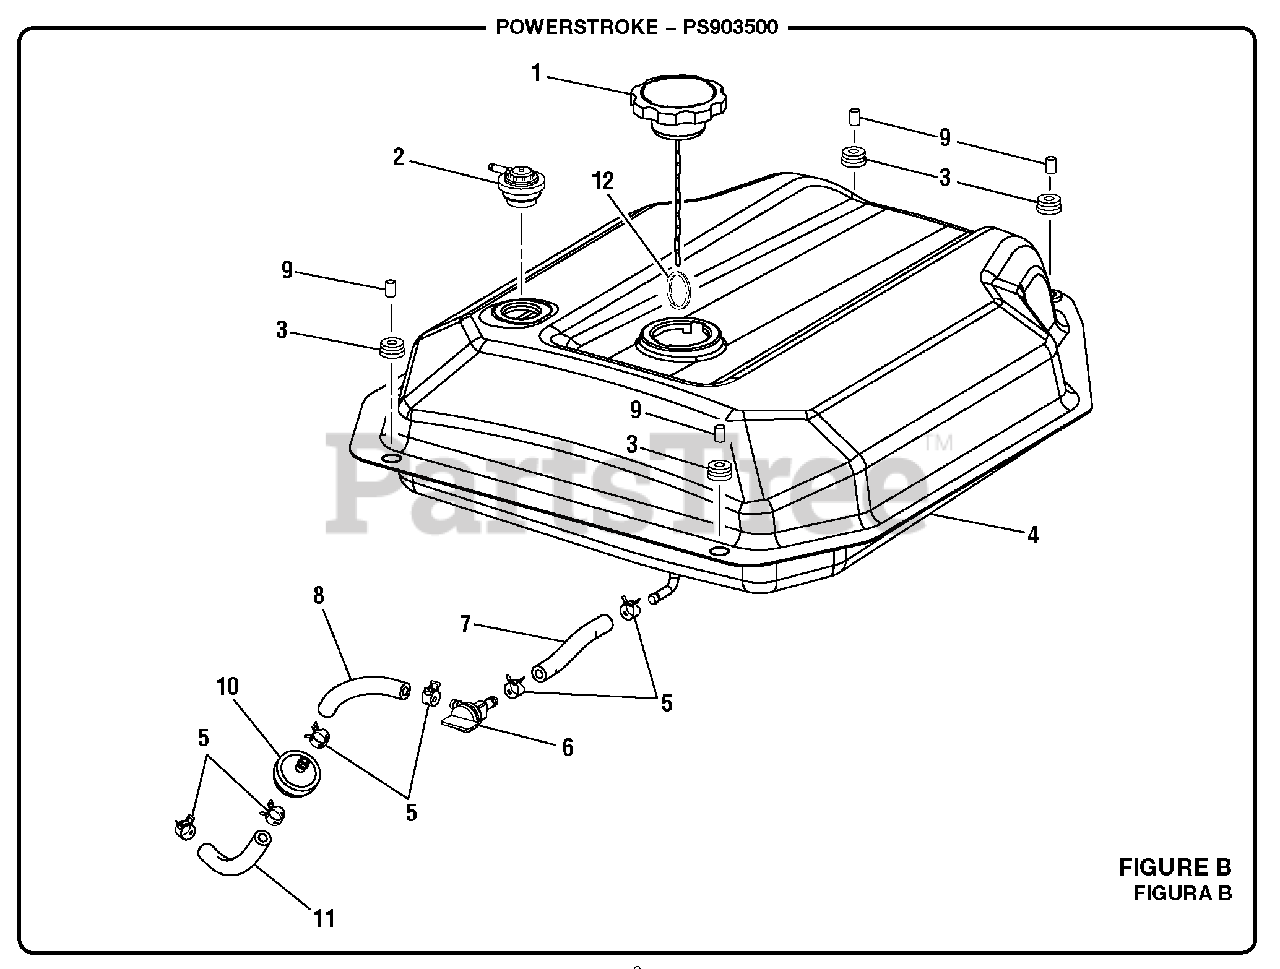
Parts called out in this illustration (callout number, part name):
1	Fuel Tank Cap
2	Fuel Tank Vapor Vent
4	Fuel Tank
5	Fuel Line Clamp (1/2 in.)
6	Fuel Shut Off Valve
7	Fuel Line (90 mm)
8	Fuel Hose (110 mm)
10	Fuel Line Filter
11	Fuel Hose (110 mm)
12	Ring Clip
